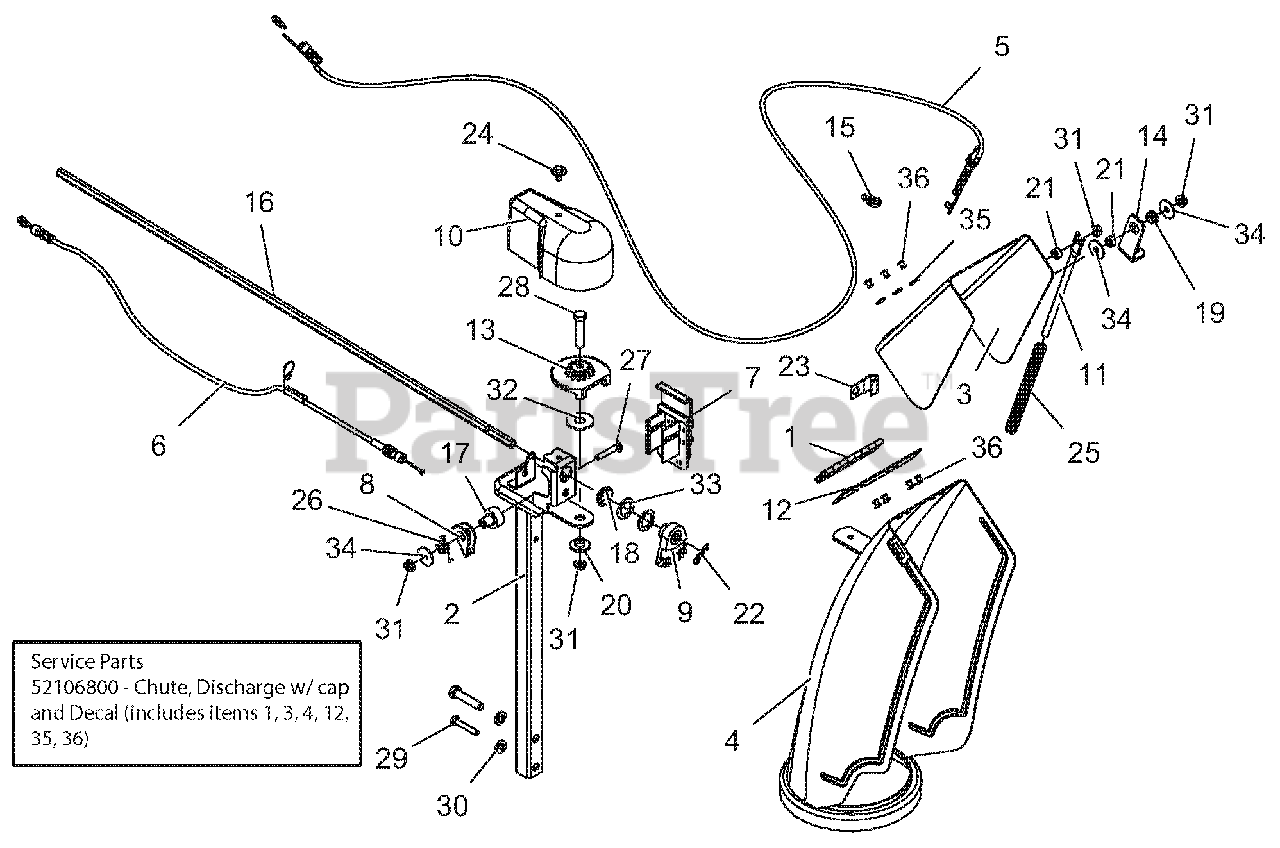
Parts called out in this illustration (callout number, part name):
2	PEDESTAL, CHUTE - QUICK STICK
3	CAP,LARGE,REMOTE
4	CHUTE,DISCHARGE,NOTCHED,QT
5	CABLE, DEFLECTOR - DELUXE
6	CABLE,CHUTE LOCK,PLAT/SHO
7	HOLDER W LARGE SHEAR BOLT /NUT
8	ARM, LOCKING
9	GEAR, CHUTE-ACTUATION
10	COVER, CHUTE GEAR
11	ROD, DEFLECTOR CAP
12	CAP SEAL 5.50
13	GEAR, CHUTE
14	BRACKET, CABLE ANCHOR
15	CLIP, CABLE GUIDE
16	ROD, HEX - CHUTE ROTATION
17	BUSHING, LOCK ARM
18	BUSHING, POLYLINER-.75 SNAPIN
19	BUSHING, POLYLINER-.50 SNAPIN
20	BSHG-FLG .265X.477X.375X1.00
21	BSHG-SLV .265X.500X.219
22	PIN-HAIR INT .08X.18X1.18 YWZC
23	J-CLAMP
24	SCR-TAP .25-20X.50 LGHWH TR YZ
25	SG-COMP .08X.40X6.50 14#/IN
26	SG-TORS
27	@BLT-RDHDSQNK .25-20X1.50 G5YZ
28	@BLT-HEX .38-16X1.75 GR5 YWZC
29	@BLT-HEX .25-20X1.50 GR5 YWZC
30	@WSHR-LK .38X.094 REG YWZC
31	@NUT-LK-CTR-FLG .25-20 YWZC
32	WSHR-FLT-NYL .515X1.375X.093
33	WSHR-FL-STL.754X1.125X.062YWZC
34	WSHR-FL-STL .281X1.000X.063
35	WSHR-FL-STL .196X.500X.06 YZ
36	RVT-POP .187 YZ
